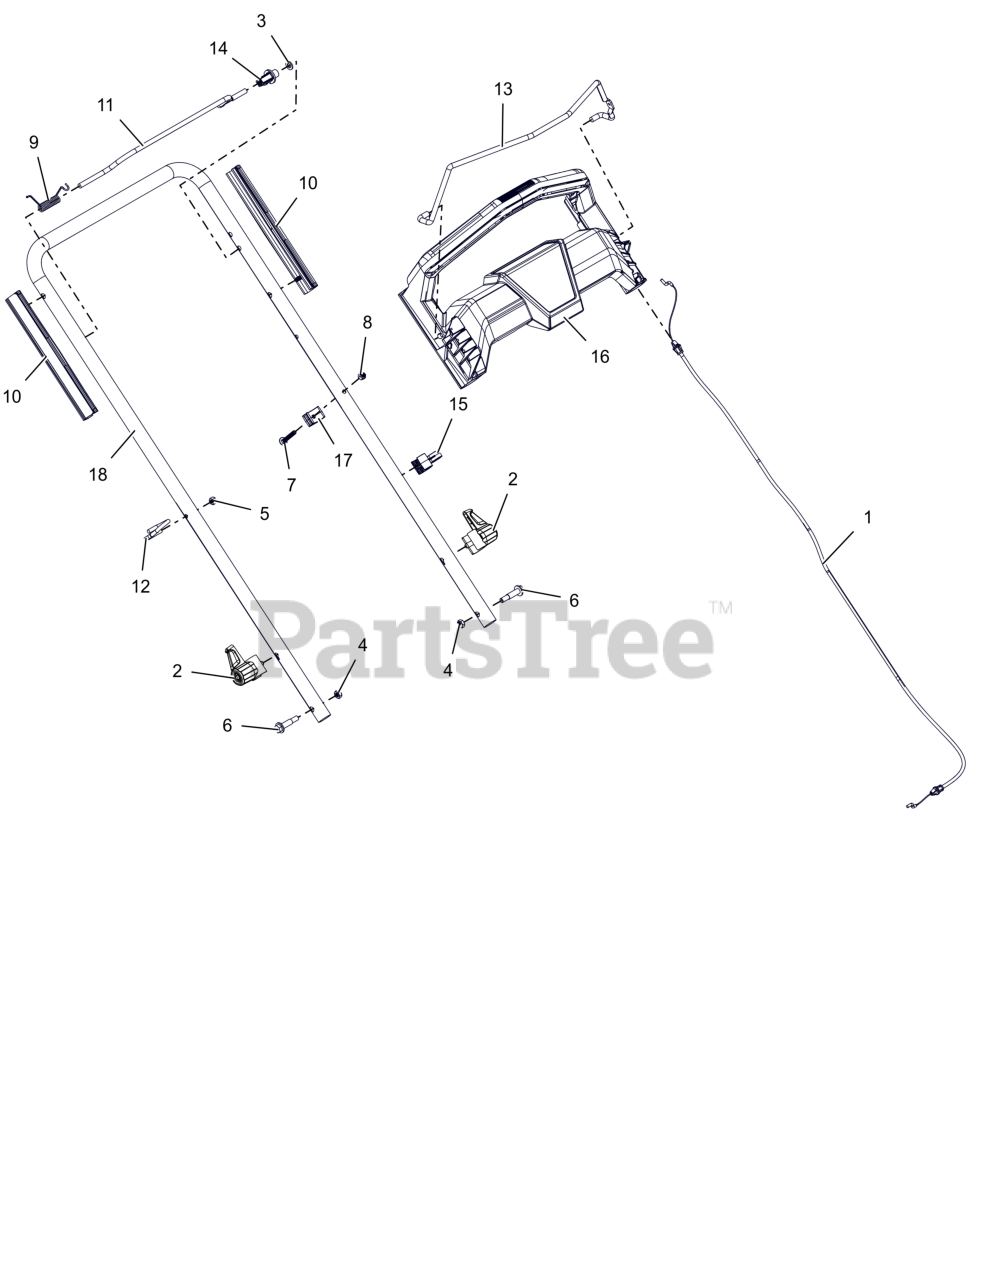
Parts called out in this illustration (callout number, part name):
1	CABLE, RWD OP
2	ASM, HANDLE ADJUSTER
3	WSHR-FL-STL, .328 X .625 X .051
4	NUT, NYLOC 5/16-18
5	NUT, NYLOC 1/4-20
6	BLT, SHLDR HWH .65X1.015X 5/16-18
7	BOLT, CARRIAGE 1/4-20X1.75
8	NUT, NYLOC 1/4-20
9	SPRG, TORSION - REFLEX
10	GUIDE, HANDLE - REFLEX
11	BAIL, REFLEX
12	GUIDE, STARTER ROPE
13	BAIL, OPC - REFLEX (GRAY)
14	CAM, REFLEX
15	GUIDE, CABLE
16	COVER, HANDLEBAR - REFLEX
17	CLAMP, CABLE - TRANSMISSION
18	HANDLEBAR, DUAL BLADE (BLACK)
